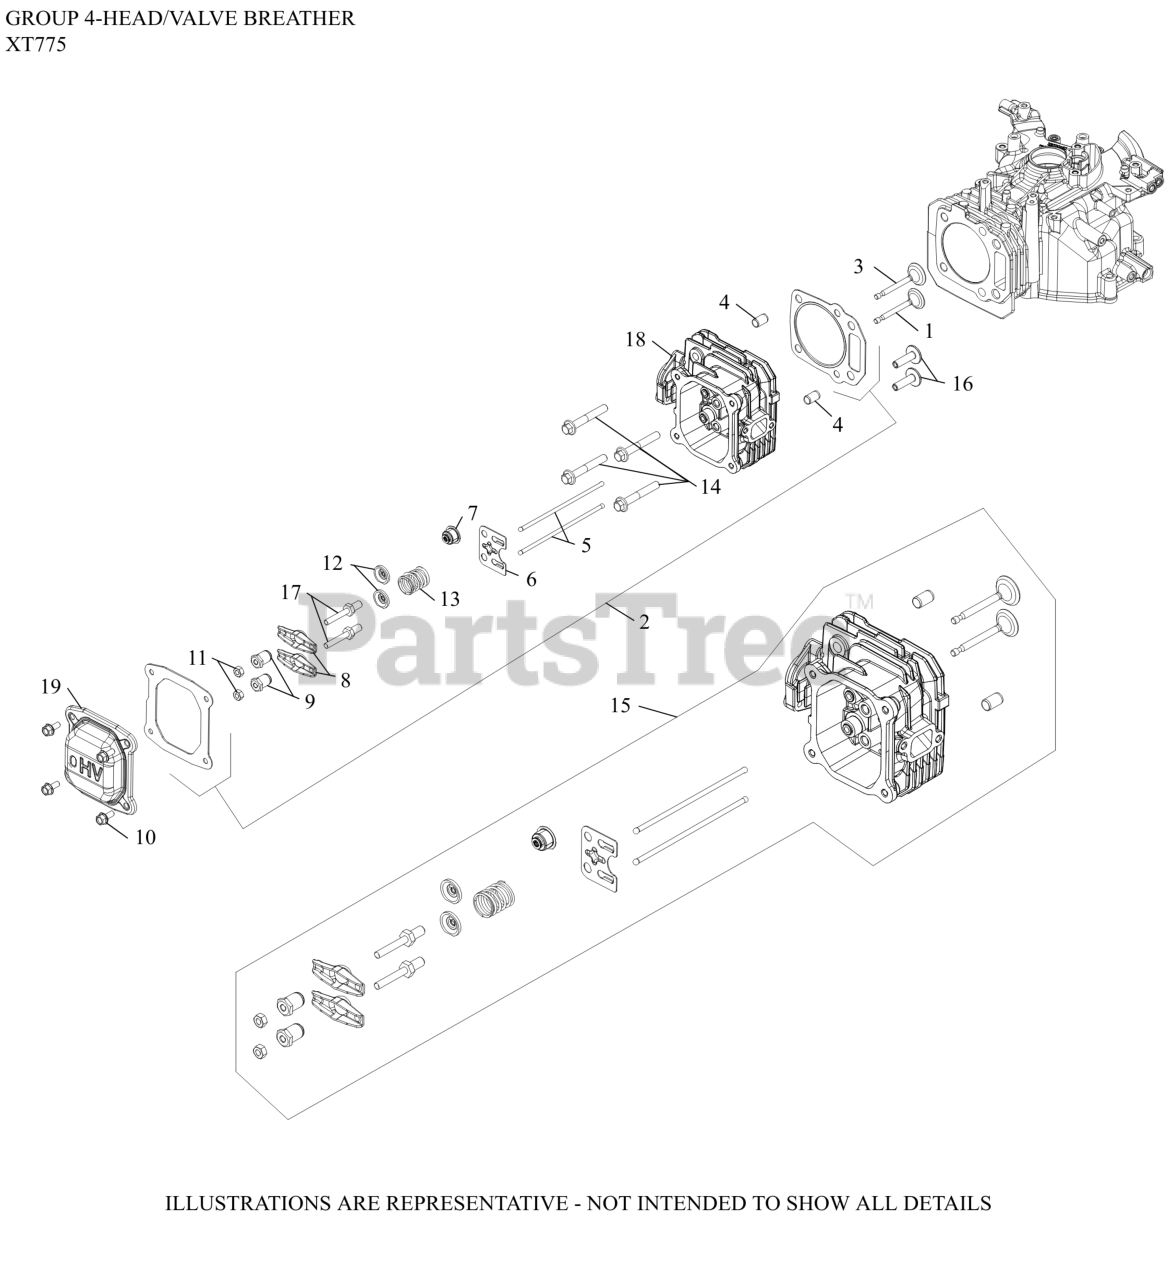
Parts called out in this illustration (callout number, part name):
1	VALVE, EXHAUST
2	KIT, HEAD GASKET-USE 14 841 34-S (XT)
3	VALVE, INTAKE
4	DOWEL, CYLINDER HEAD-(#1438013S)
5	ROD, PUSH
6	PLATE, PUSHROD GUIDE
7	SEAL, VALVE STEM
8	ARM, ROCKER
9	PIVOT, ROCKER ARM
11	NUT, HEX JAM
12	RETAINER, VALVE SPRING
13	SPRING, VALVE
14	SCREW, HEX FLANGE M8
15	KIT, VALVE TRAIN
16	LIFTER, VALVE
17	STUD, ROCKER ARM
18	HEAD, CYLINDER
19	COVER, VALVE
